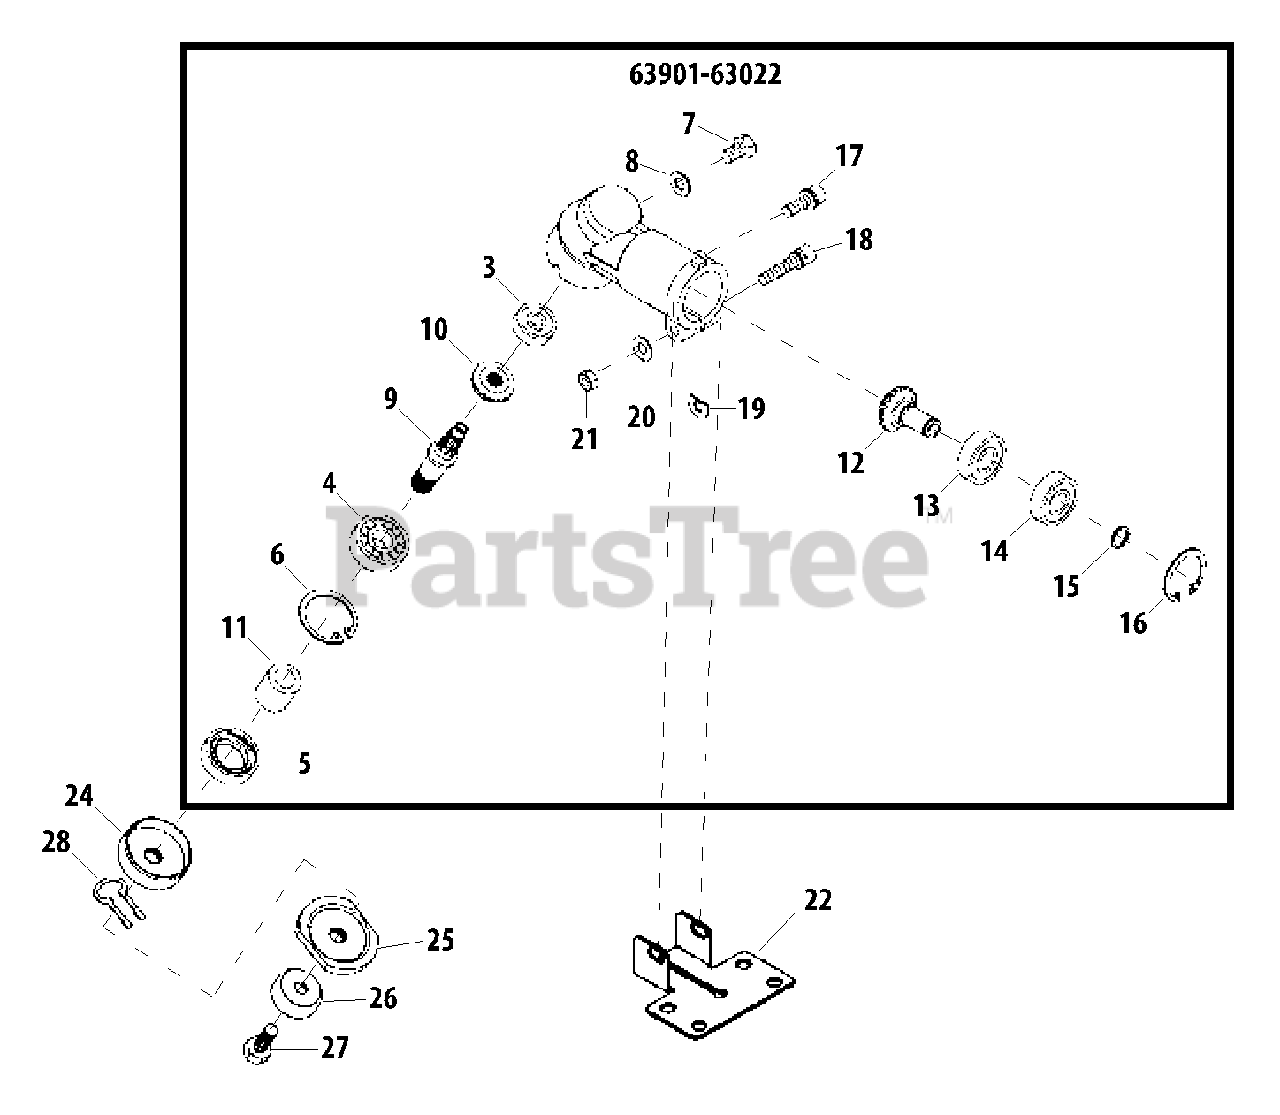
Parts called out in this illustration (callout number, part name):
3	BEARING, BALL 626 DDU
4	BEARING, BALL 6000
5	SEAL, OIL
6	RING, SNAP Ø26
7	BOLT M6×10
8	WASHER
9	SHAFT, GEAR
10	GEAR, BEVEL
11	SPACER
12	GEAR, PINION
13	BEARING, BALL 608
14	BEARING, BALL 608ZZ
15	RING, SNAP
16	RING, SNAP Ø22
17	BOLT M5×16
18	BOLT M5×35
19	D-WASHER
20	WASHER 5 MM
21	NUT M5
22	PLATE, SHIELD MOUNTING
24	PLATE, ADAPTOR - UPPER
25	PLATE, ADAPTOR - LOWER
26	GUARD, BOLT
27	BOLT M7×18
28	CLIP, BLADE
63901-63022	GEAR CASE ASSY
